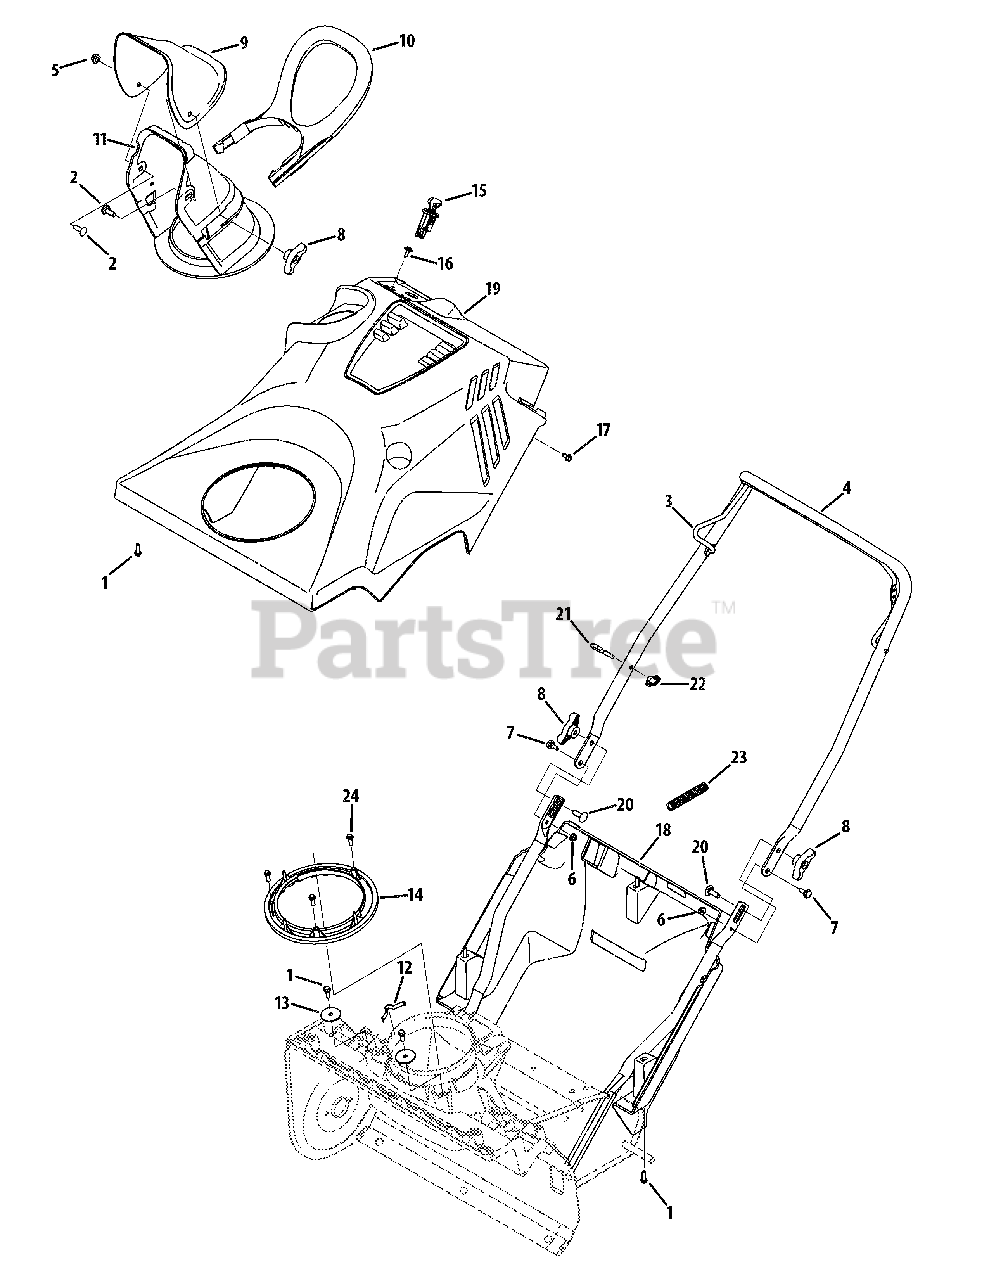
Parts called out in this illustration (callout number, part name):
1	Screw, 1/4-15 x 0.75
2	Carriage Bolt, 5/16-18 x .750
3	Auger Bail
4	Upper Handle
5	Flange Lock Nut, 5/16-18
6	Flange Lock Nut, 1/4-20
7	Shoulder Screw, 1/4-20 x .375 x .148
8	Wing Knob, 5/16-18
9	Upper Chute
10	Chute Handle
11	Lower Chute
12	Chute Adjustment Spring
13	Flat Washer, .28 x 1.51 x .066
14	Chute Ring
15	Ignition Switch Assembly
16	Hex Washer Screw, 1/4-15 x .50
17	Hex Washer Screw, 1/4-20 x .625
18	Bottom Cover
19	Top Cover
20	Carriage Screw, 5/16-18 x 1.00
21	Eye Bolt, 1/4-20
22	Handle Knob
23	Conduit
24	Hex Washer Screw, 1/4 x .750
